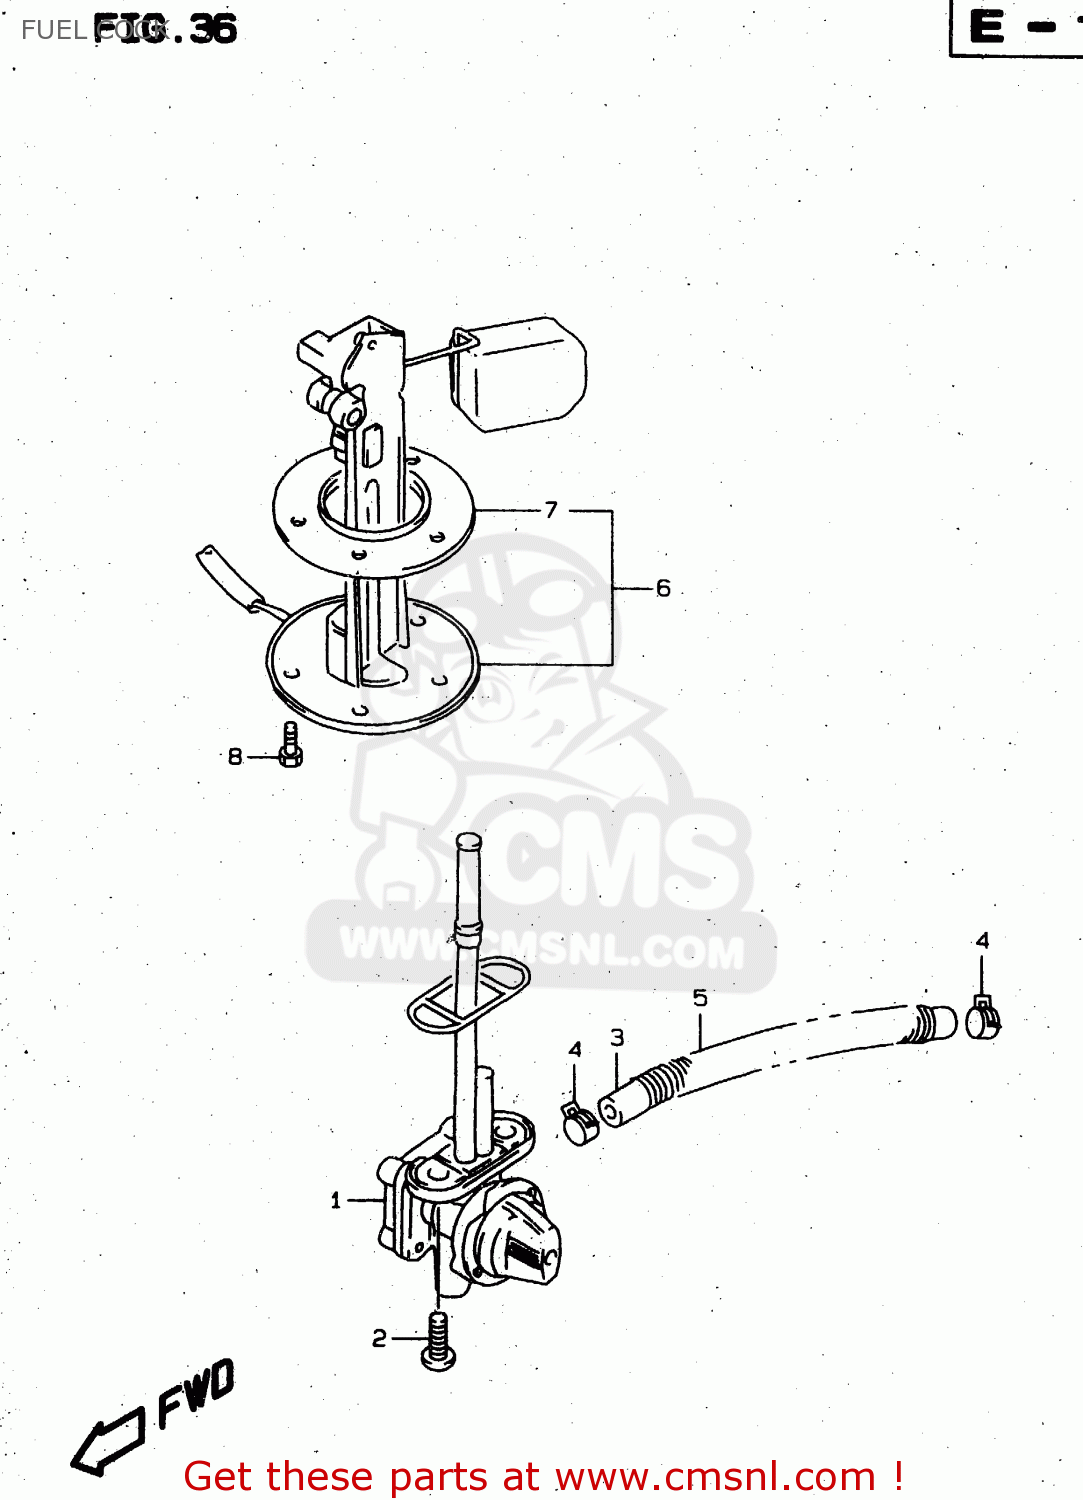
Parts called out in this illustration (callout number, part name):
1	COCK ASSY,FUEL
2	SCREW
3	HOSE(7X12X600)
4	CLIP
5	SPRING
6	GAUGE ASSY,FUEL LEVEL SENDER
7	GASKET (NAS)
8	BOLT 5X10
